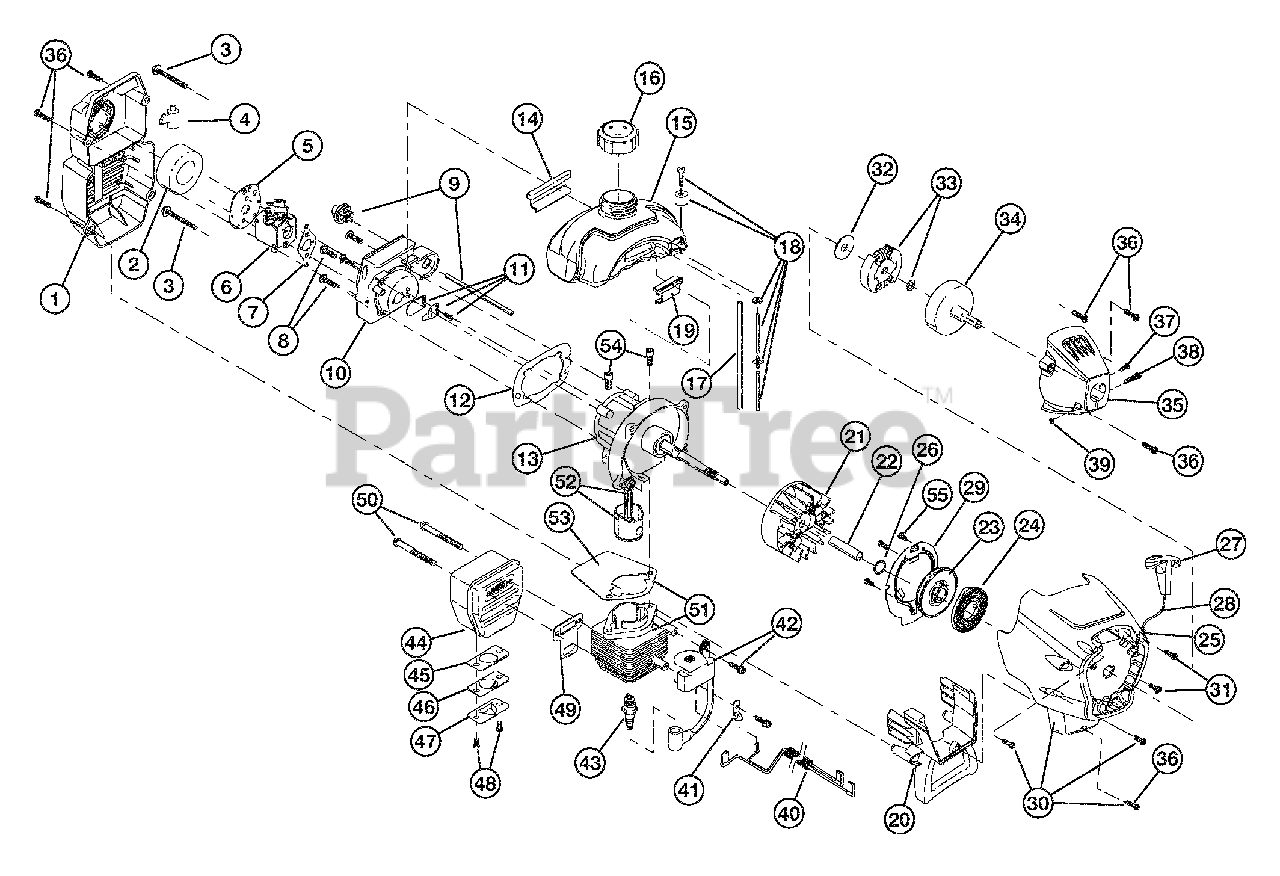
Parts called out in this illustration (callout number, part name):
1	Air Cleaner/Muffler Cover Assembly
2	Air Cleaner Filter
3	Carburetor Mounting Screw Assembly
4	Choke Extension
5	Choke Plate
6	Carburetor Assembly
7	Carburetor Gasket
8	Carb Mount Screw
9	Primer and Hose Assembly
10	Carb Mount Assembly
11	Reed Assembly
12	Carburetor Mount Gasket
13	Crank Case Service Assembly
14	Rear Mounting Pad
15	Fuel Tank Assembly
16	Fuel Cap Assembly
17	Fuel Return Line
18	Fuel Line Assembly
19	Front Mounting Pad
20	Shroud Extension & Stand
21	Flywheel Assembly
23	Recoil Pulley
24	Recoil Spring
25	Rope Guide
26	Pulley Retainer
27	Pull Handle
29	Pressure Plate Assembly
30	Starter Housing Assembly
31	Housing Screw
32	Clutch Washer
33	Clutch Rotor Assembly
34	Clutch Drum Assembly
35	Clutch Cover Assembly
36	Cover Screw
37	Anti-Rotation Screw
38	Clamping Screw
39	Clamping Nut
40	Wire Leads and Sleeve
41	Ground Tab
42	Module Assembly
43	Spark Plug
44	Muffler Assembly
45	Spark Arrestor Screen
46	Spark Arrestor Plate
47	Spark Arrestor Hood
48	Spark Arrestor Screw
49	Exhaust Gasket
50	Muffler Mounting Bolt Assembly
51	Cylinder Assembly
52	Piston and Rod Assembly
53	Cylinder Gasket
54	Cylinder Bolt
55	Screw
